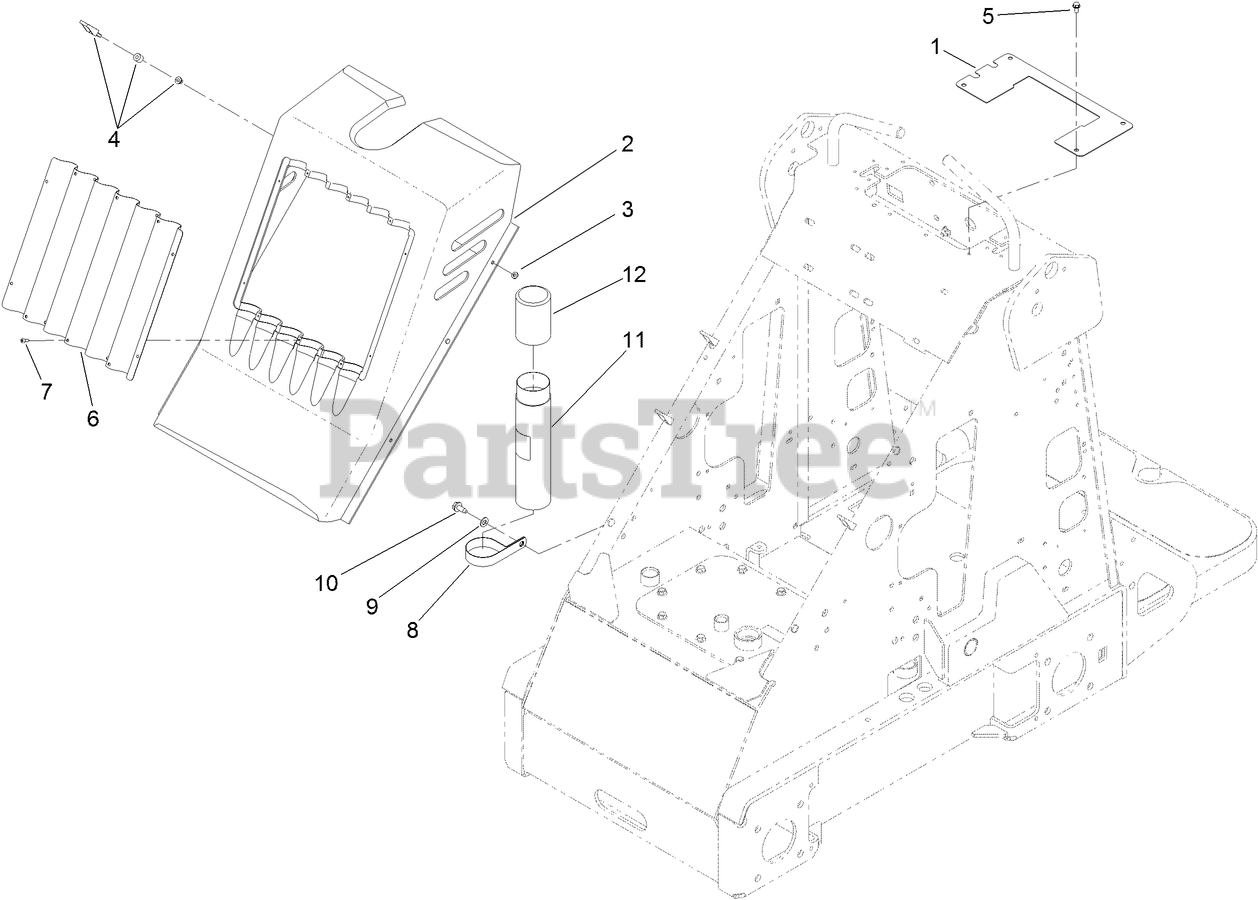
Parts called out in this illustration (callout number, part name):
1	PLATE-COVER
2	COVER-HOOD
3	WASHER
4	LATCH-SWELL
5	SCREW-HWH
6	GRILLE-SCREEN
7	SCREW-PPH
8	CLAMP-R
9	WASHER-PLAIN
10	SCREW-HWHTF
11	TUBE-MANUAL
12	CAP-HOUSING
